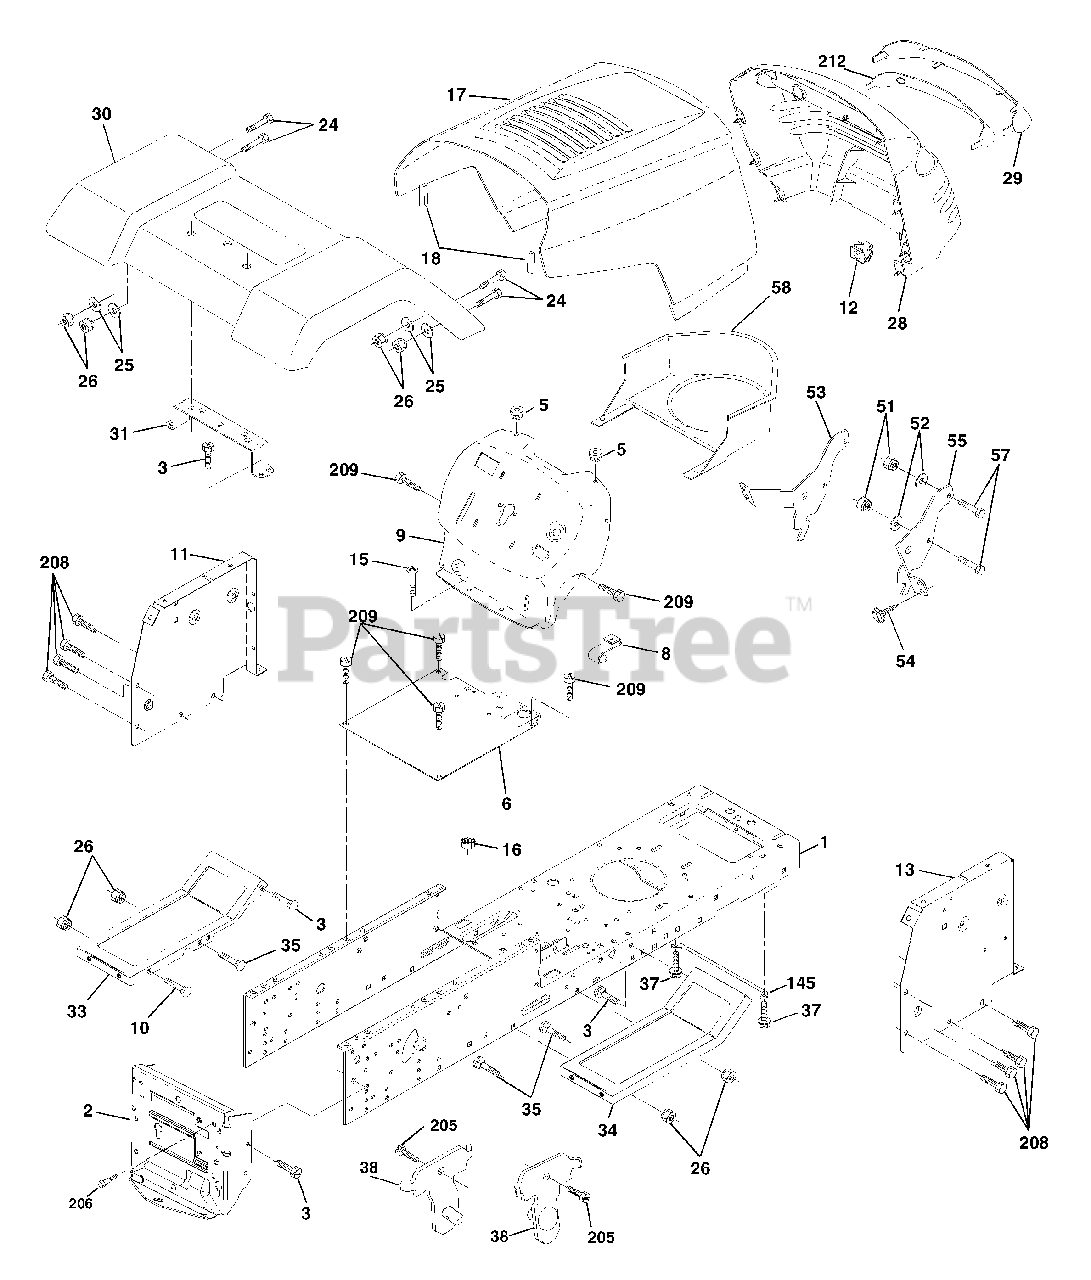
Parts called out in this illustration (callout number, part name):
1	Chassis
2	Drawbar
3	Screw 3/8-16 x 3/4
5	Bumper Hood/Dash
6	Saddle Flat Lt
8	Clip Retainer Slide-On
9	Dash
10	Bolt Rd Hd Sqnk. 3/8-16 Unc x 1
11	Panel Asm. Dash Lh
12	Clip Tinnerman Grile P/L
15	Screw Mach Trhd 5/16-18 Unc x 3/4
16	Nut Keps 5/16-18 Unc
17	Hood
18	Bumper Hood
24	Bolt Fin Hex 3/8-16 Unc x 1 Gr. 5
25	Washer 13/32 x 13/16 x 12 Ga.
26	Nut Lock Hex w/Insert 3/8-16 UNC
28	Grill/Lens Asm
29	Lens Grille Private label
31	Bracket Fender
33	Footrest
34	Footrest
35	Bolt Rd Hd Sht. Sqnk. 3/8-16 x 3/4
37	Screw Thdrol 5/16-18 x 1/2 Tyt
38	Bracket Asm. Pivot Mower Rear
51	Nut Lock Hex W/Ins. 1/4-20
52	Washer 9/32 x 7/8 x 16 Ga.
53	Bracket Grille LH
54	Screw Hex Wshd 8-18 x 7/8
55	Bracket, Grille RH
57	Bolt Fin Hex 1/4-20 x .75
58	Air Duct Private Label
145	Rod Pivot Chassis/Hood
205	Screw Thdrol 3/8-16 x 1/2
206	Bolt shoulder 5/16-18
208	Screw Thdrol 3/8-16 x 1/2
209	Screw Hex Wsh Thdrol 3/8-16
212	Insert Lens Reflector
